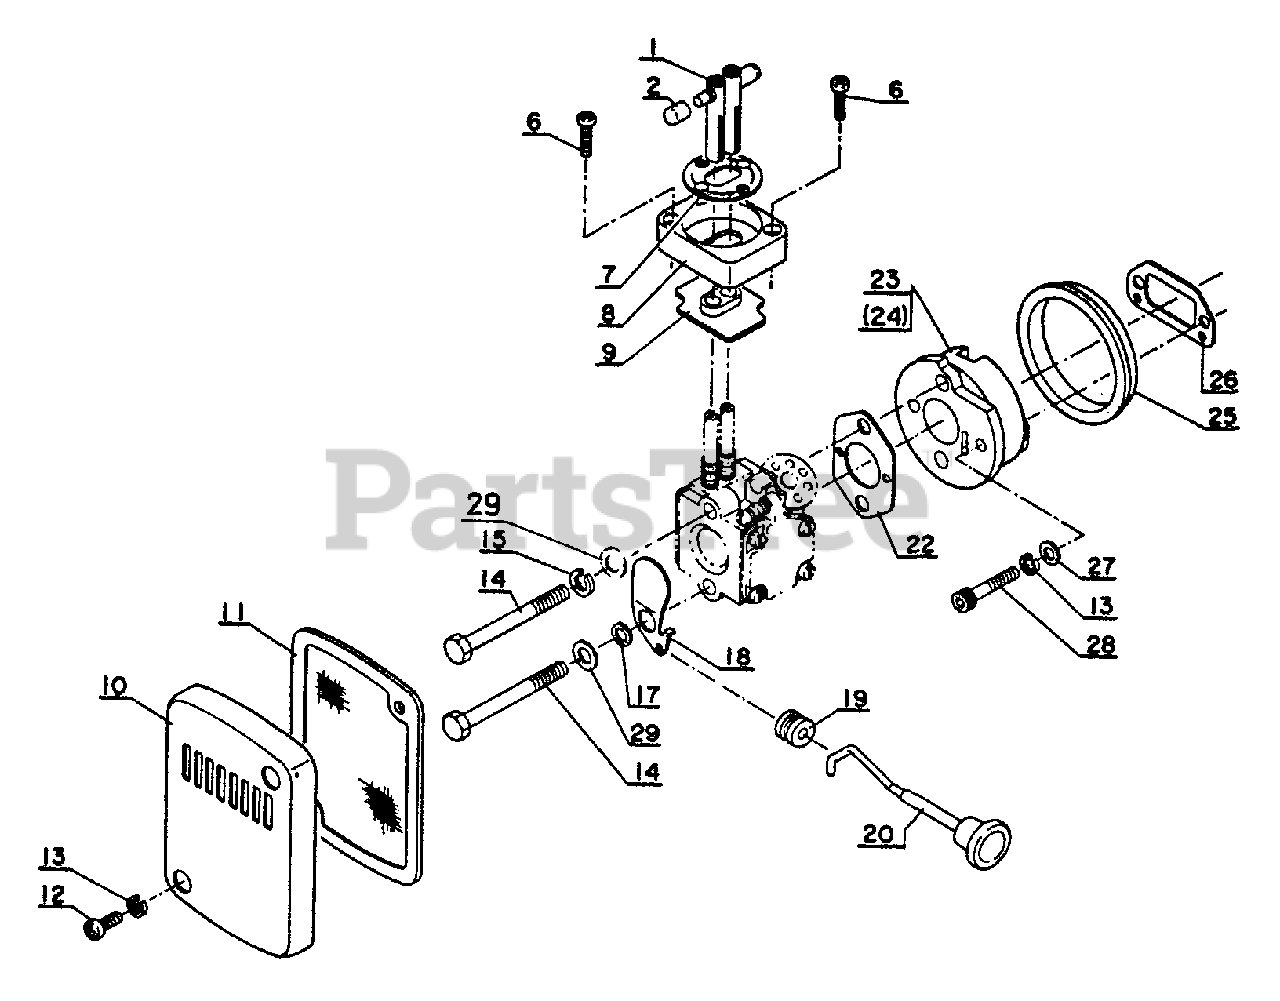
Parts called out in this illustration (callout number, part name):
1	ADJUSTING ARM
2	ADJUSTING KNOB
6	SCREW - 3X10
7	LABEL - DECOMPRESSION
8	FRAME
9	GROMMET
10	COVER, AIR FILTER
11	FILTER, AIR
12	SCREW - 4X12
13	LOCKWASHER - 4
14	BOLT - 5X40
15	LOCKWASHER - 5
17	WASHER - 5
18	SHUTTER, CHOKE
20	ROD, CHOKE
22	GASKET, INTAKE
23	INSULATOR, INTAKE
25	GROMMET
26	GASKET, INTAKE
27	WASHER - 4
28	SCREW - 4X20
29	WASHER - 5
